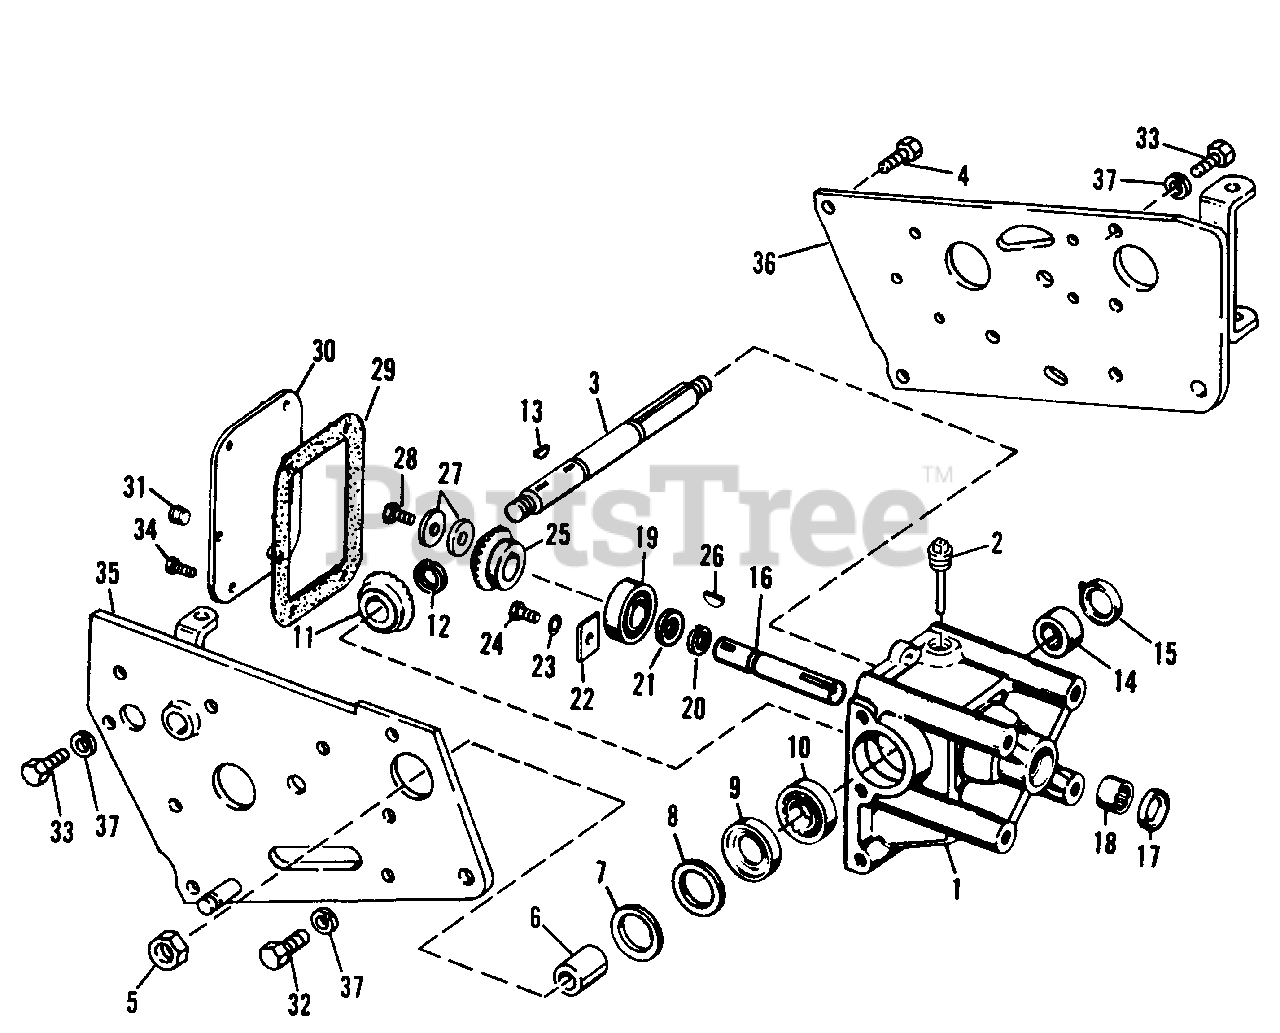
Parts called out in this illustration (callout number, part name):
1	HOUSING, Gear, Bevel
2	PLUG ASSEMBLY
3	SHAFT, Driven
4	CAPSCREW, Hex, 7/16-14 x 1-1/4" lg.
5	NUT, Hex, Jam, 3/4"-16
7	SHIM (As Required)
10	BEARING, Ball
11	GEAR, Bevel, Driven
12	RING, Retaining
13	KEY
14	BEARING, Needle
16	SHAFT, Driven
18	BEARING, Needle
19	BEARING, Ball
20	RING, Retaining
22	PLATE, Clamp, Bearing
23	LOCKWASHER, 5/16"
24	CAPSCREW, Hex, 5/16-18 x 5/8" lg.
25	GEAR, Bevel, Driven
26	KEY
28	CAPSCREW, Hex
32	CAPSCREW, Hex, 7/16" -14 x 1" lg.
33	CAPSCREW, Hex, 7/16"-14 x 1-1/4" lg.
34	CAPSCREW, Hex, 1/4"-20 x 5/8" lg.
35	PLATE ASSEMBLY, Side, R.H.
36	PLATE ASSEMBLY, Side, L.H.
37	LOCKWASHER 7/16"
